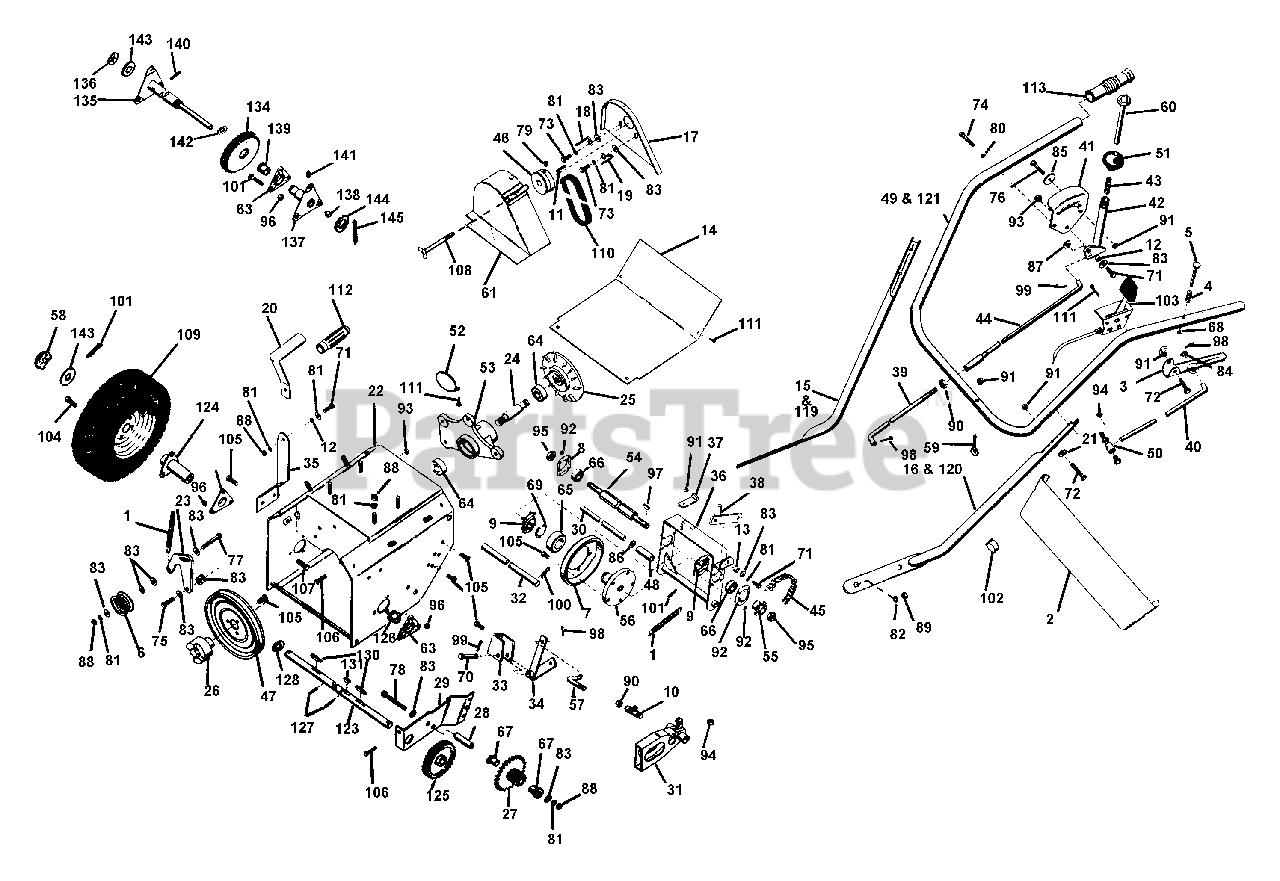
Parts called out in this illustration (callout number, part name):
1	SPRING
2	HANDLE BAR PANEL
3	CLUTCH HANDLE
4	SG-COMP ??X.44X?? WLD 10
5	CLUTCH LOCK PIN
6	IDLER
7	FRICTION DISC
8	BEARING FLANGE
9	BEARING FLANGE
10	BALL JOINT
12	SPACER BUSHING .5 X .32 X .21
13	SPACER BUSHING .5 X .32 X .163
14	BOTTOM COV
15	R H LOWER HANDLE BAR
16	L H LOWER HANDLE BAR
17	INNER BELT GUARD
18	R H BELT FINGER
19	L H BELT FINGER
20	CLTCH LEVER
21	HANDLE BAR WASHER
22	TRAC FRAME
23	IDLER ARM
24	SPINDLE
25	DRIVE PLATE
26	JAW COUPLING
27	PINION & SPROCKET
28	PINION STUB SHAFT
29	SUPPORT BRACKET
30	BRACKET PIN
31	SLIDING FORK
32	FORK SHAFT
33	LEVER BRACKET
34	TRANSFER LEVER
35	CLTCH BRCKT
36	DISC BRCKT
37	NEUTRAL CATCH
38	THROWOUT LEVER
39	LOWER SHIFT ROD
40	CLTCH ROD
41	SHIFT QUADRANT
42	SHIFT HANDLE
43	SPRING
44	SHIFT ROD
45	ROLLER CHAIN
46	ENGINE SHEAVE
49	UPPER HANDLE BAR
50	BALL JOINT
51	SHIFT BALL
53	BEARING HOUSING
54	HEX SHAFT
55	9 TOOTH SPROCKET
56	FRICTION DISC HUB
57	CONNECTING LINK
58	HUB CAP
59	ROD HANGER EYEBOLT
60	SHIFT RELEASE HANDLE
61	OUTER BELT GUARD
62	CARB COVER
63	SUPPORT, BEARING
64	BRG-BALL .750X1.750X.50
65	BRG-BALL 1.25X2.18X.63
66	BRG-BALL .500X1.38X.437
67	BSHG-FLG .625X.750X.500X.875BR
68	RG-RTNG-EXT .250X.031
69	RG-RTNG-EXT 1.250X.050
70	CLEVIS PIN
71	BLT-HEX .31-18X.63 PL GR 2
72	BLT-HEX .38-16X1.25 PL GR 2
73	BLT-HEX .38-16X1.25 PL GR 2
74	BLT-HEX .38-16X1.25 PL GR 2
75	BLT-HEX .38-16X1.50 PL GR2
76	BLT-HEX .44-14X1.25 PL GR2
77	BLT-HEX .44-14X1.25 PL GR2
78	BLT-HEX .44-14X1.25 PL GR2
79	SCR-SET .38-16X.50 SKHCUP OH
80	WSHR-LK .250X.077 HVY PL
81	WSHR-LK .312X.097 PL HVY
82	WSHR-LK .375X.115 HVY PL
83	WSHR-FL-STL .38X.875X.083 PL
84	BRG-CUP1.980X.420
85	WSHR-FL-STL .531X1.062X.095 PL
86	BRG-NEEDLE .625X.812X.50
87	WSHR-FL-STL.406X.812X.065PL
88	NUT-JAM .375-16 PL
89	NUT-JAM .375-16 PL
90	NUT-HEX .312-24 PL
91	NUT-LK-CTR .250-20 PL
92	NUT-LK TOP 10-24 PL
93	NUT-LK .312-18 GR A PL
94	NUT-LK-CTR .312-24 PL
95	NUT-LK-CTR .50-20 PL
96	NUT-LK-FLG .250-20 PL
97	KEY-WDRF .188X.875X.375 SAE11
98	PIN-COTR .09X.75 PL
99	PIN-COTR .12X1.0 PL
100	PIN-COTR .09X.75 PL
101	PIN-COTR .09X.75 PL
102	Cable Clamp
103	THROTTLE CONTROL
104	BRG-CUP 2.441X.562
105	BLT-SERHFWH .31-18X.50 PL
106	BLT-SCRHFWH .38-16X.50 PL
107	SCR-SLTR-SERNK .25-20X.62 PL
108	BLT-HFWH .31-24X3.62 PL
109	T/WHL ASSY
109	TIRE 4.10/3.50X6 2PLY
109	WHL 6 IN O.D.
110	V-BELT, SAE 380-RAW EDGE
111	SCR-TAP 10-12X.50 CRPH PL A
113	GRIP
114	Serial No. Label
115	DISCHARGE CAUTION LABEL
116	DISCHARGE CAUTION LABEL
117	DISCHARGE CAUTION LABEL
118	DISCHARGE CAUTION LABEL
119	R H LOWER HANDLE BAR
120	L H LOWER HANDLE BAR
121	UPPER HANDLE BAR
122	MOWER IN-OUT LABEL
123	AXLE SHAFT
124	WHEEL HUB
125	SPUR GEAR, FELLOWS 35T .750 ID
126	BSHG-FLG .750X1.000X.625X1.500
127	PIN-ROLL .250X1.25
128	WSHR-FL-STL .531X1.062X.095 PL
129	WSHR-FL-STL .755X2.000X.125
130	KEY-WDRF .188X.875X.375 SAE11
131	KEY-WDRF .188X.875X.375 SAE11
132	PIN-COTR .09X.75 PL
133	MOWER IN-OUT LABEL
134	Differential Assembly
135	R H AXLE SHFT
136	PUSHNUT
137	L H AXLE
138	BSHG-SLV .562X.625X.625 BRZ
139	BSHG-FLG.875X1X.625X1.250 BR
140	PIN-ROLL .188X1.25
141	HYDRAULIC DRIVE FITTING
142	WSHR-FL-STL .531X1.062X.095 PL
143	WSHR-FL-STL .755X2.000X.125
144	BRG-CONE .750X.61
145	PIN-COTR .12X1.0 PL
146	MOWER IN-OUT LABEL
